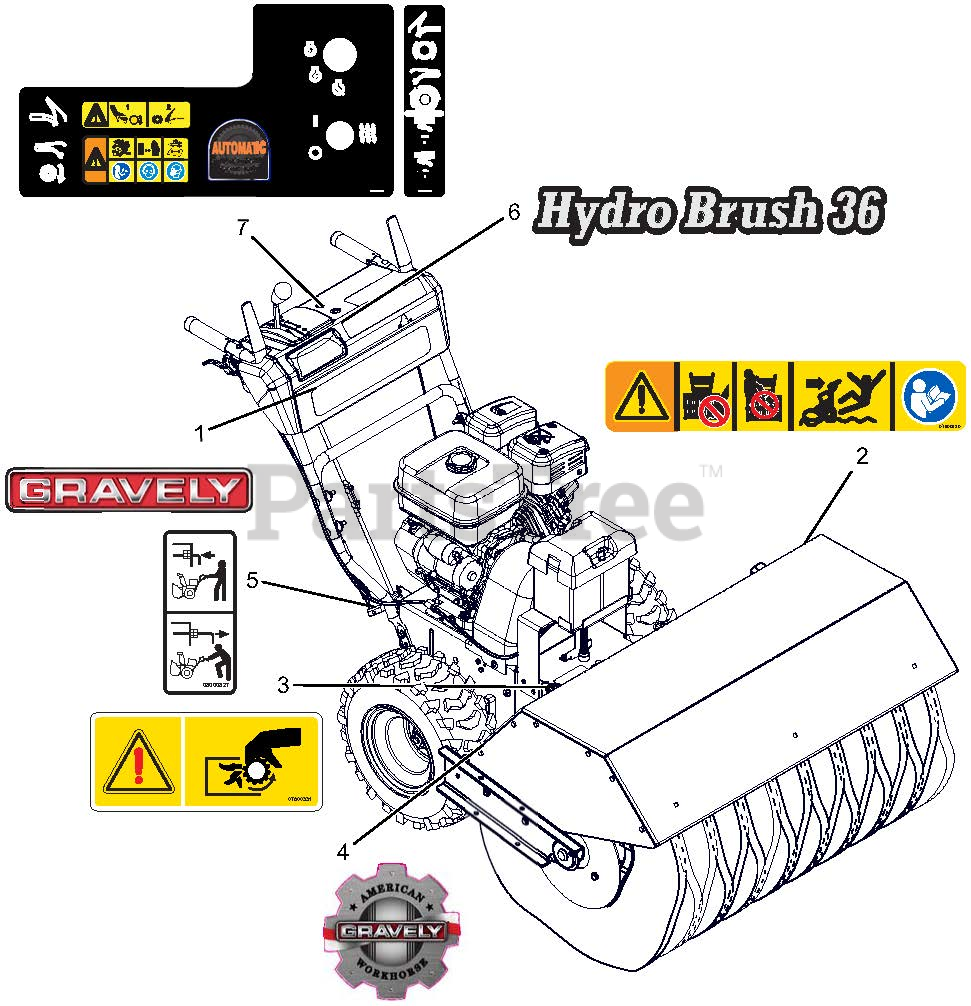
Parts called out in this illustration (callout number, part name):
1	DECAL, 15" GRAVELY LOGO REV
2	DECAL, DANGER - POWER BURSH CE
3	DECAL, DANGER - PTO WARNING
4	DECAL, GRAVELY HERITAGE-LARGE
5	DECAL, HYDRO PRO BYPASS
6	DECAL, HYDRO BRUSH 36
7	DECAL, CONTROL - BRUSH 12V
